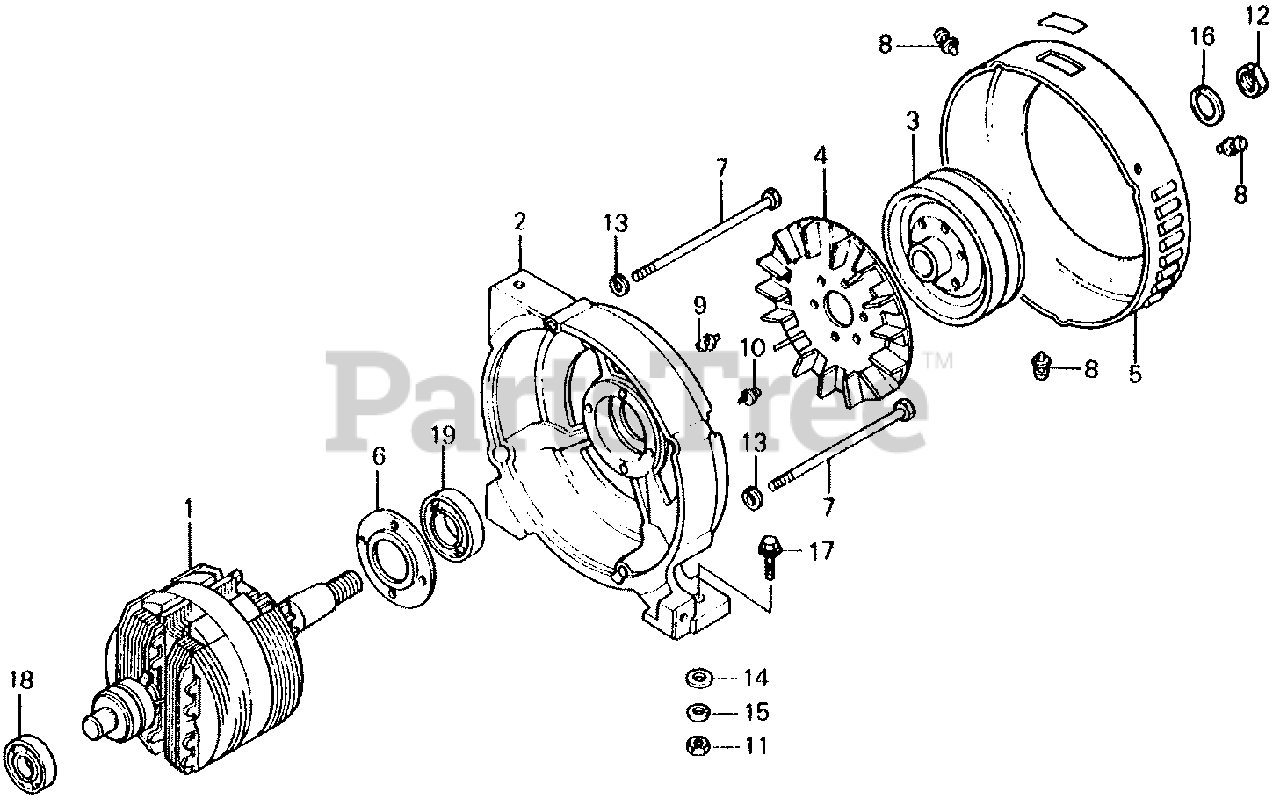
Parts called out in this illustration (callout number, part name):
2	HOUSING, FR. *NH31* (MCKINLEY WHITE)
3	PULLEY, GENERATOR (104MM)
5	COVER, FAN *NH31* (MCKINLEY WHITE)
6	COVER B, BEARING
7	BOLT, HEX. (6X118)
7	BOLT, HEX. (6X120)
8	SCREW-WASHER (4X6)
9	SCREW-WASHER (4X25) (NOT AVAILABLE)
10	SCREW-WASHER (5X10)
11	NUT, HEX. (8MM)
12	NUT, HEX. (18MM) (NOT AVAILABLE)
13	WASHER, PLAIN (6MM)
14	WASHER, PLAIN (8MM)
15	WASHER, SPRING (8MM)
16	WASHER, SPRING (18MM) (SOURCE: VINTAGE PARTS INC.)
17	BOLT, FLANGE (8X28)
18	BEARING, RADIAL BALL (6203UU)
19	BEARING, RADIAL BALL (6205UU)
